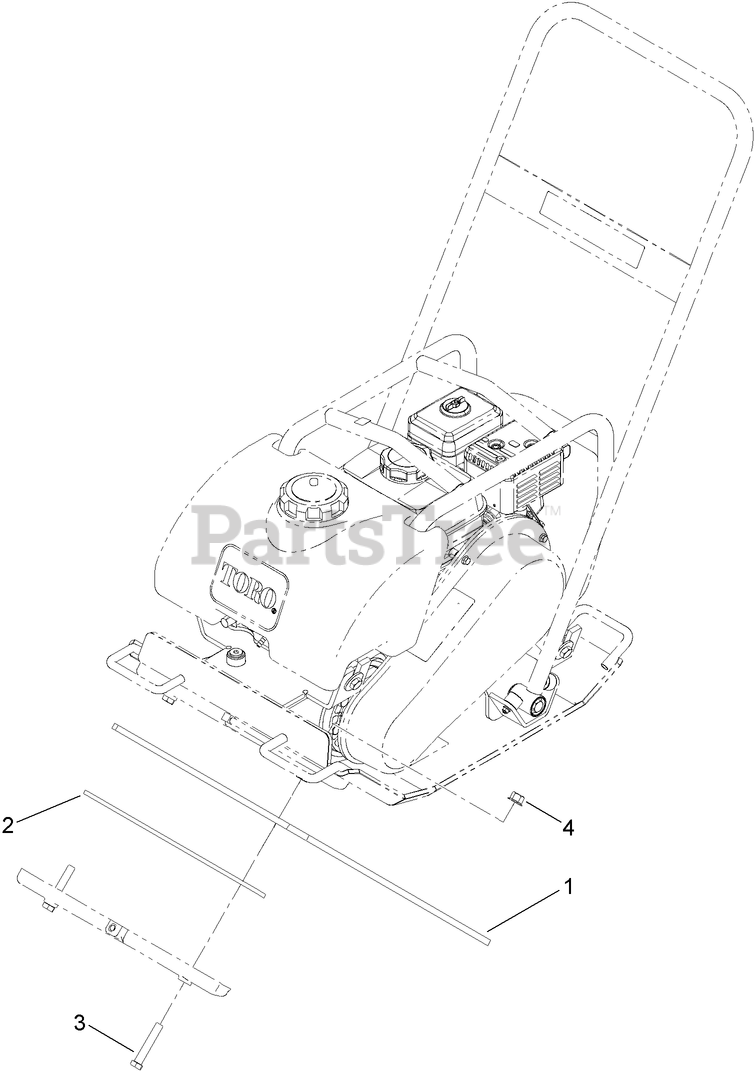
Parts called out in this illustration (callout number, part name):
1	MAT-PAVER PLATE, RUBBER
2	CLAMP-PLATE, PAVER
3	SCREW-HH
4	NUT-LOCK, HHF
